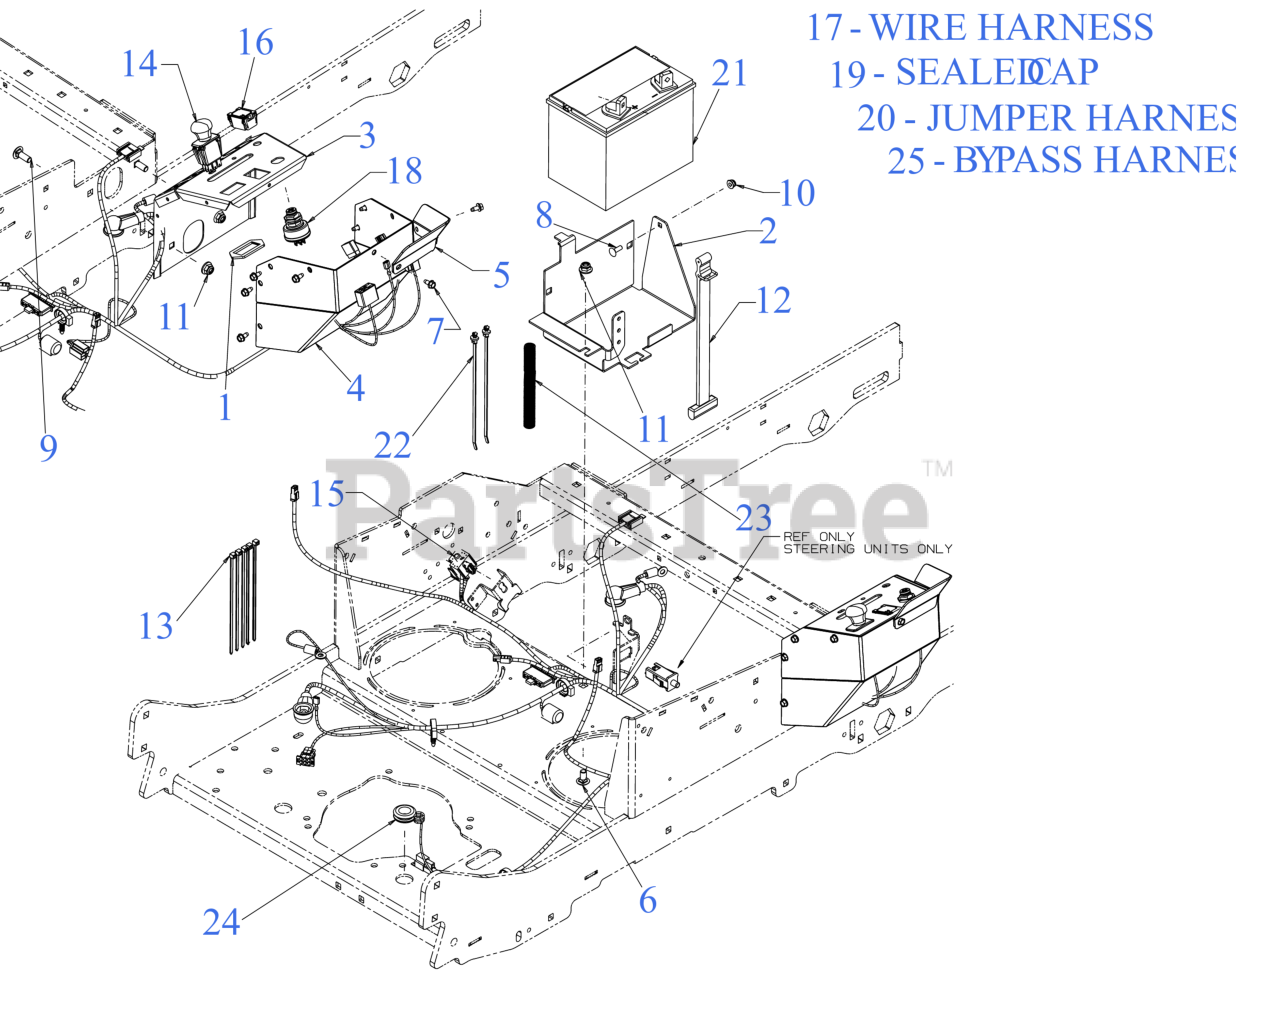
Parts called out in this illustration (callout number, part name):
1	BRACKET-PTO SWITCH
2	BATTERY MOUNTING BRACKET
3	CONTROL POD - RH
6	CARRIAGE BOLT 3/8-16 x .750 GR5
7	SCREW 1/4-20 X.500
8	SCREW 1/4-20 x .75 GR5
9	CARRIAGE BOLT 3/8-16 x 1.00 GR5
10	FLANGE LOCK NUT
12	BATTERY RETAINER STRAP
13	7" CABLE TIE
14	PTO SWITCH (BLACK KNOB) TEXT SYM
15	3 POLE SWITCH ( NC-NO-NO)
17	WIRE HARNESS ASSEMBLY KOH/KAW EFI
18	KEY SWITCH (3 POSITION)
19	SEALED CAP ASSEMBLY
20	JUMPER HARNESS (W/RELAY)
21	BATTERY (230 CCA AGM U1-280)
21	BATTERY
21	Purchase Battery Locally
22	CABLE TIE
23	CONVOLUTED CONDUIT 1"
24	RUBBER GROMMET
25	BYPASS HARNESS
